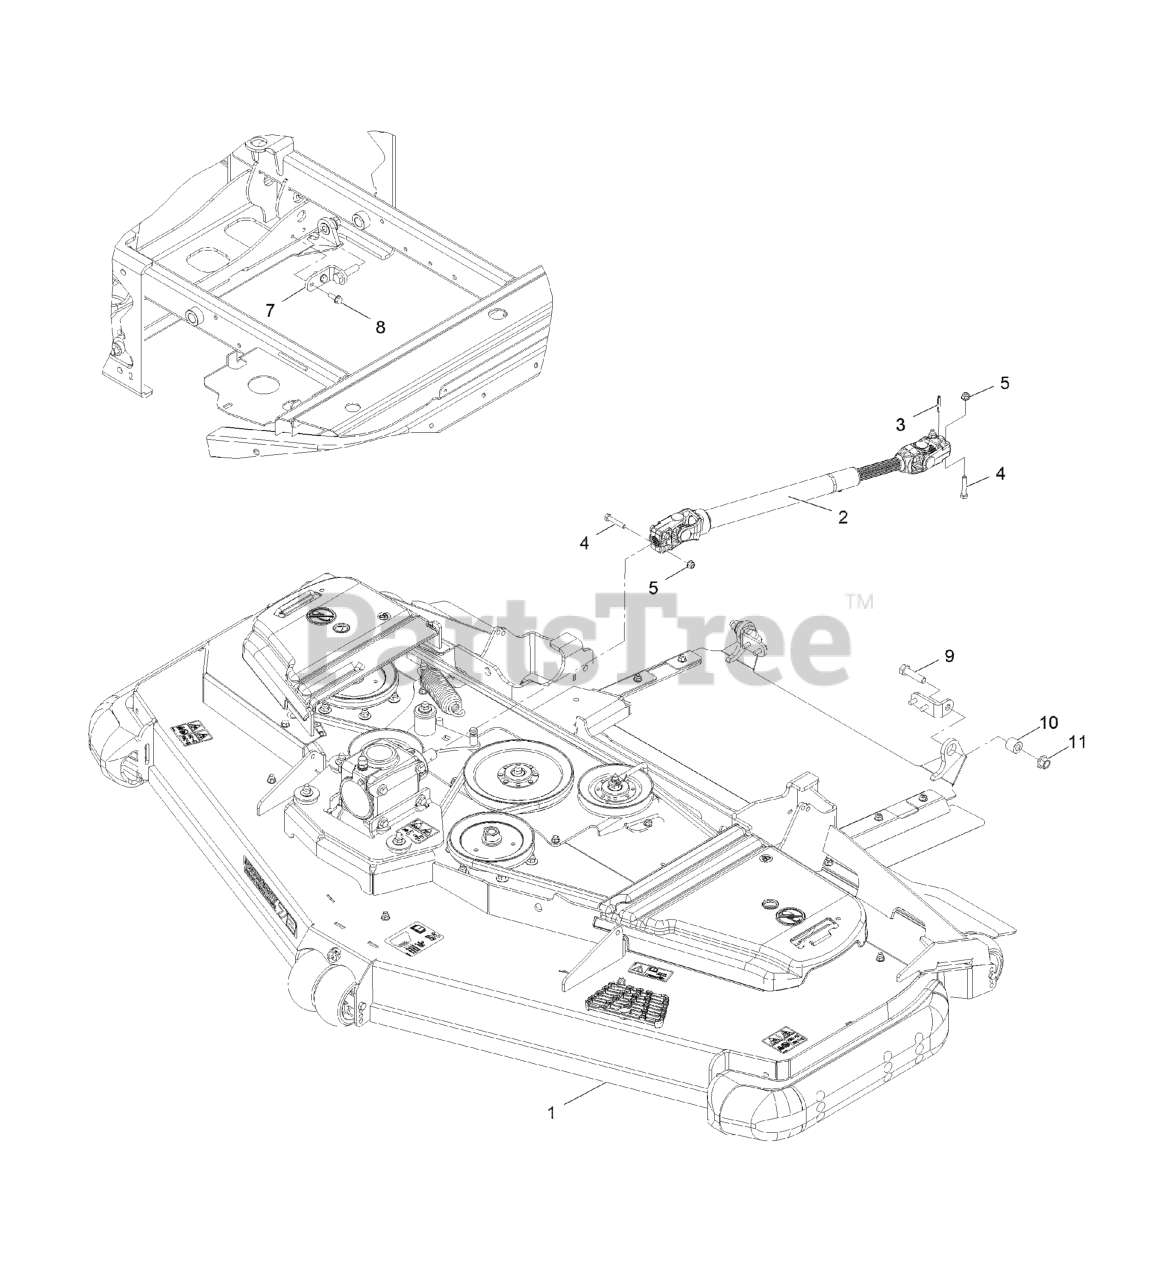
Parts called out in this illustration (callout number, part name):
1	Deck ASM-72Rd
2	DRIVESHAFT ASM
3	PIN-ROLL
4	SCREW-HH
5	NUT-HF, NI
6	Discharge Tunnel ASM
7	BRACKET-DISCHARGE
8	SCREW-TAPTITE
9	SCREW-HH
10	BUSHING-SLEEVE
11	Nut-Lock 1/2-13
